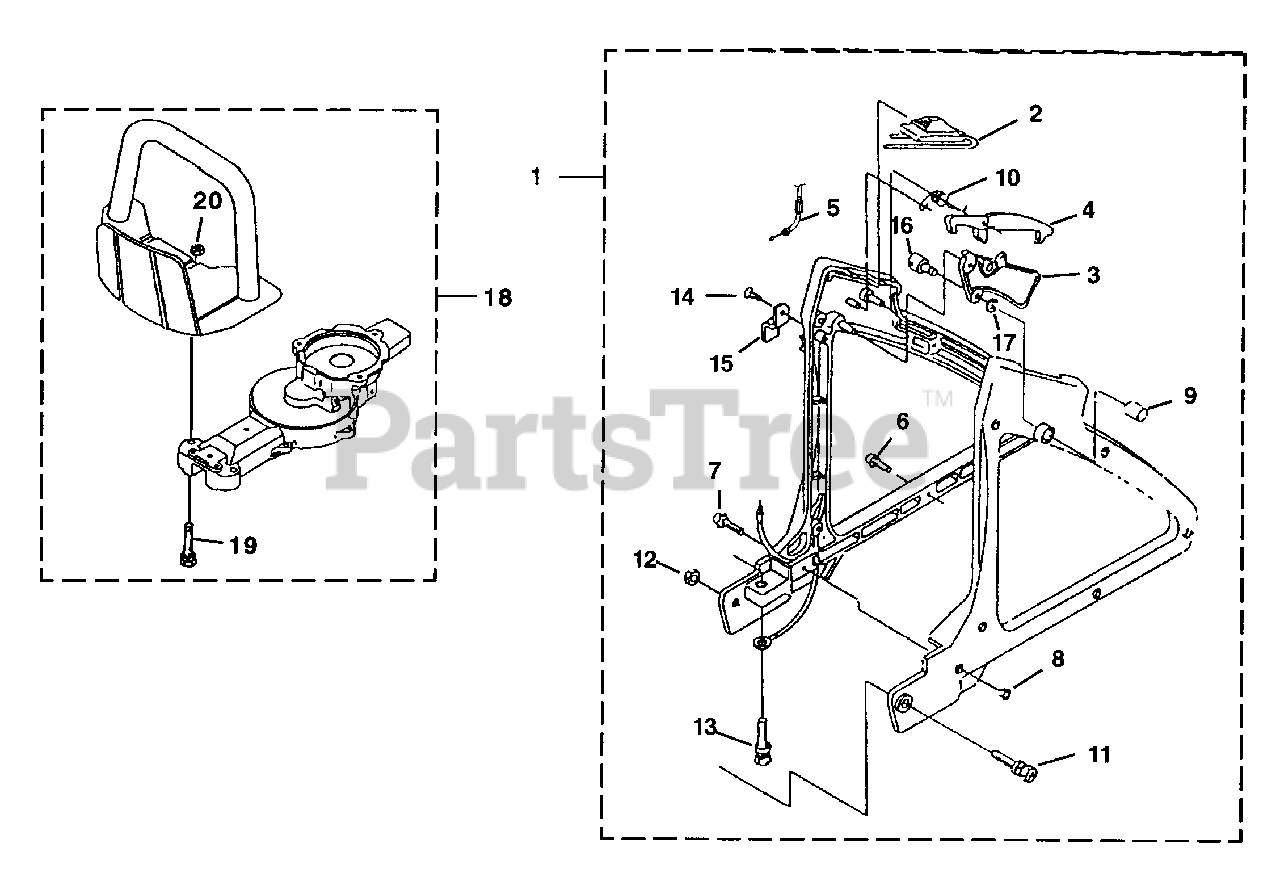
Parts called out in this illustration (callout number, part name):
1	REAR HANDLE COMPLETE
2	SWITCH ASSEMBLY
3	TRIGGER-Throttle
4	LATCH-Throttle
5	CABLE - Throttle
6	SCREW (M4 x 16 W SW)
7	SCREW (M4 x 30 W SW)
8	NUT (M4)
11	SCREW (M6 x 50 W SW & PW)
12	NUT (M6)
13	SCREW (M6 x 40 W SW & PW)
14	SCREW (M4 x 10)
15	HOLDER-Cable
16	CABLE-Swivel
17	SNAP RING
18	FRONT HANDLE ASSEMBLY
19	SCREW (M6 x 35 W SW & PW)
20	NUT (M6)
